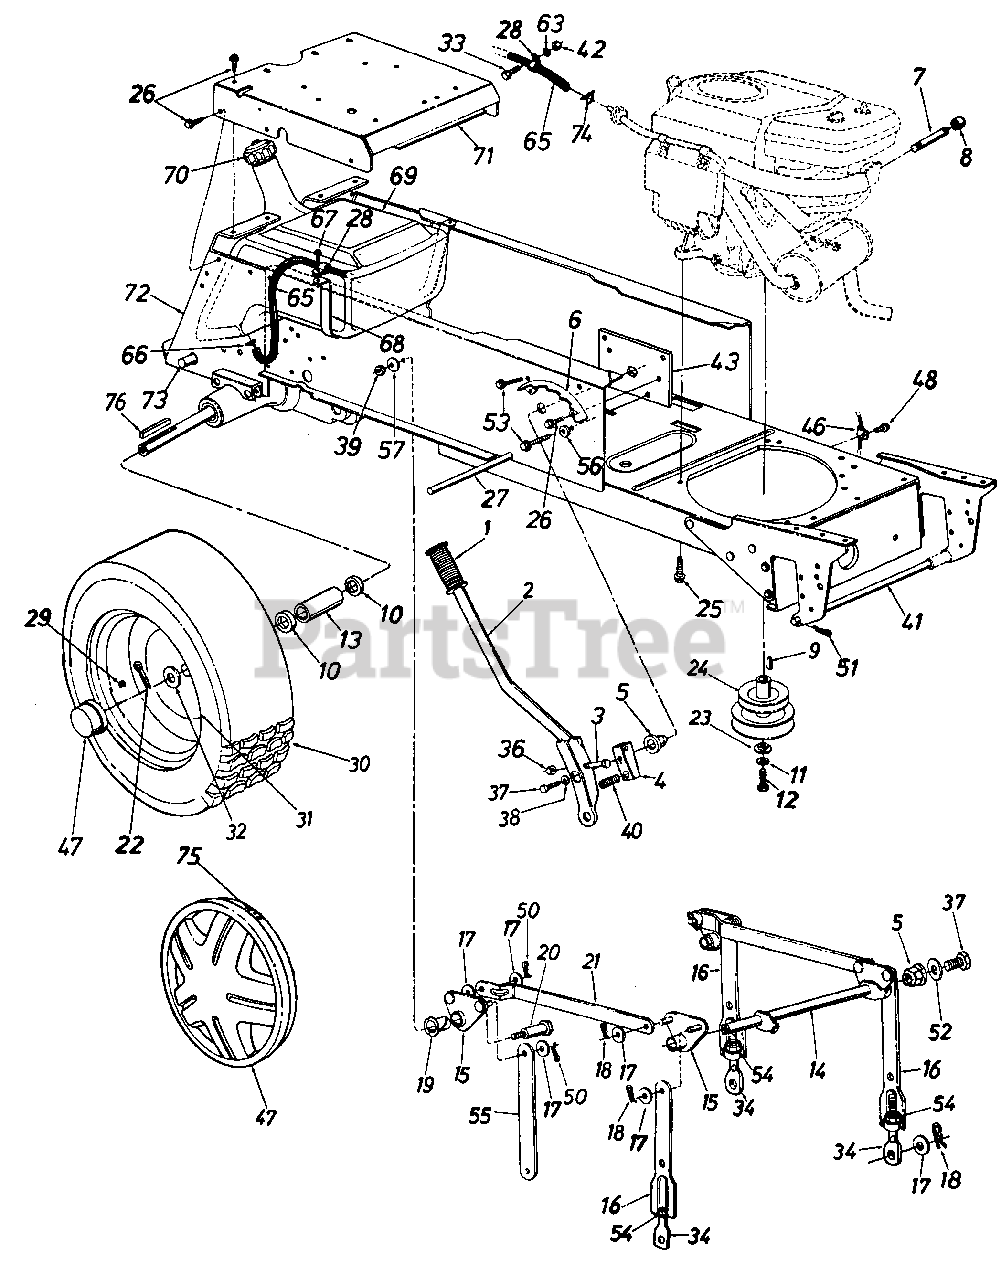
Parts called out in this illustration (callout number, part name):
1	Grip
2	Lift Handle Ass'y.
3	Hex Bolt 5/16-18 x 1.5" Lg.
4	Lift Shaft Drive
5	Plastic Hex Brg. 518" I.D.
8	Pipe Cap 3/8-18 Npt.
9	Sq. Key 1/4" x 1/4" x 1.50" Lg.
10	Fl-Wash. 1.03" I.D. x 1.62" O.D.
11	L-Wash. 7/16" I.D.
12	Hex Scr. 7/16-20 x 1.50" Lg.
13	Spacer 1.0" I.D. x 1.25" O.D.
14	Lift Shaft Ass'y.
15	Lift Pivot Brkt. Ass'y.
17	Fl-Wash. 1/2" I.D. x 1.00" O.D. x .090"
18	Hairpin Cotter
19	Nyliner 518" I.D. x .88" Lg.
20	Shld. Bolt 518" Dia. x .96" Lg. 3/8-16
23	Flat Wash. .44" I.D. x 1.25" O.D. x .17"
24	Two-Step Engine Pulley
25	Hex Wash. Hd. Scr. 3/8-16 x 1.25" Lg.
26	Hex Thd. Rolling Scr. 5/16-18 x.75" Lg.
27	Running Board Rod
28	Clamp
29	Air Valve
33	Hex Bolt 1/4-20 x .62" Lg.
34	Eye Bolt Adj. Link 1/2-13 Thd.
36	Hex Cent. L-Nut 5/16-18 Thd.
37	Hex Bolt 5/16-24 x .62" Lg.
38	L-Wash. 5/16" I.D.
39	Hex Top L-Nut 3/8-16 Thd.
40	Compression Spring
41	Deck Connecting Rod
42	Hex Nut 1/4-20 Thd.
47	Hub Cap
48	Hex Wash. Hd. TT-Tap Scr. 1/4-20 x .5" Lg.
50	Cotter Pin .09 Dia. x 1.0" Lg.
51	Int. Cotter Pin
52	Flat Wash. .34" I.D. x 1.12" O.D. x .125"
53	Hex Wash. Hd. AB-Tap Scr. 5/16-24 x .5" Lg.
54	Hex Nut 1/2-13 Thd.
56	Fl-Wash. .344" I.D.
57	Bell-Wash. .4" I.D. x 1.13" O.D.
63	L-Wash. 1/4' I.D.
65	Fuel Line 50" Lg.
66	Hose Clamp
67	Hex AB-Tap Scr. 1/4 x .62" Lg.
68	Fuel Tank Strap
69	Gas Tank
70	Gas Gauge
71	Seat Plate
74	Hose Clamp
75	Spring Clip
76	Sq. Key 1/4" x 3" Lg.
